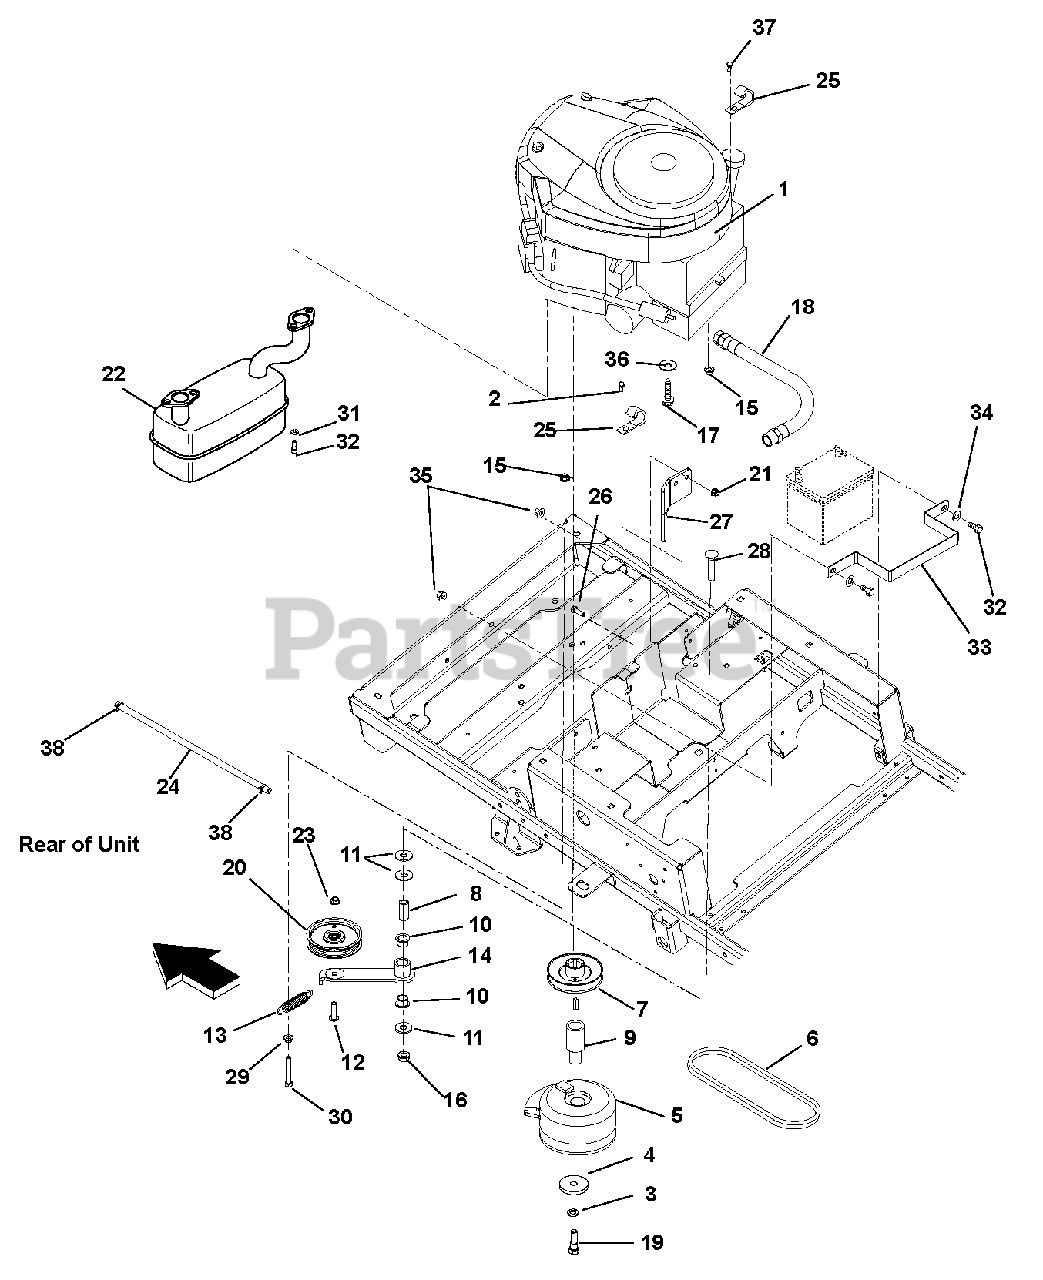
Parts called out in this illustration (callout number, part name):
1	Engine, Kawasaki FR691V (915160)
2	Screw, Tapping .250-20 x .37 Hex Washer Head
2	Clamp, Fuel Line
3	Washer, Locking .44 x .109 Regular
4	Washer, Flat Steel .469 x 2.00 x .25
5	Clutch, XL
6	Belt, HA 62.50 Wrapped
7	Pulley, V 4.5 x 1.5 AB Section with Key
8	Bushing, Sleeve .500 x .750 x 1.560
9	External, Crankshaft Lower
10	Bushing, Flange 0.75 x 0.875 x .625 x 1.125
11	Washer, Flat Steel .563 x 1.38 x .109
12	Bolt, Round Head Square Neck .38-16 x 1.50 Grade 5
13	Spring, Tension .105 x .812 x 3.88
14	Weldment, Ground Drive Idler Arm
15	Nut, 3/8-16 Flange Nyloc
16	Nut, Locking Top Flange .50-13
17	Bolt, Hex .38-16 x 1.25
18	Hose Assembly, Oil Drain
19	Bolt, Hex .44-20 x 4.50 Grade 8
20	Assembly, 4" Idler
21	Nut, .31-18 Nyloc Flange
22	Muffler, Kawasaki Twin Courage
23	Nut, Locking Top Flange .38-16
24	Fuel Hose
26	Bolt, Hex .31-18 x 1.00 Grade 5
27	Clutch Stop
28	Bolt, Round Head Square Neck .50-13 x 2.50 Grade 5
29	Nut, Flange .375-16
30	Bolt, Hex .38-16 x 2.50 Grade 5
31	Washer, Locking .31 x .078 Regular
32	Bolt, Hex .25-20 x .75
33	Bracket, Battery Hold Down
34	Washer, Flat Steel .281 x .62 x .065
35	Nut, KEPS .250-20
36	Washer, Flat Steel .406 x .812 x .065
37	Bolt, Hex .38-16 x .75 Grade 5
